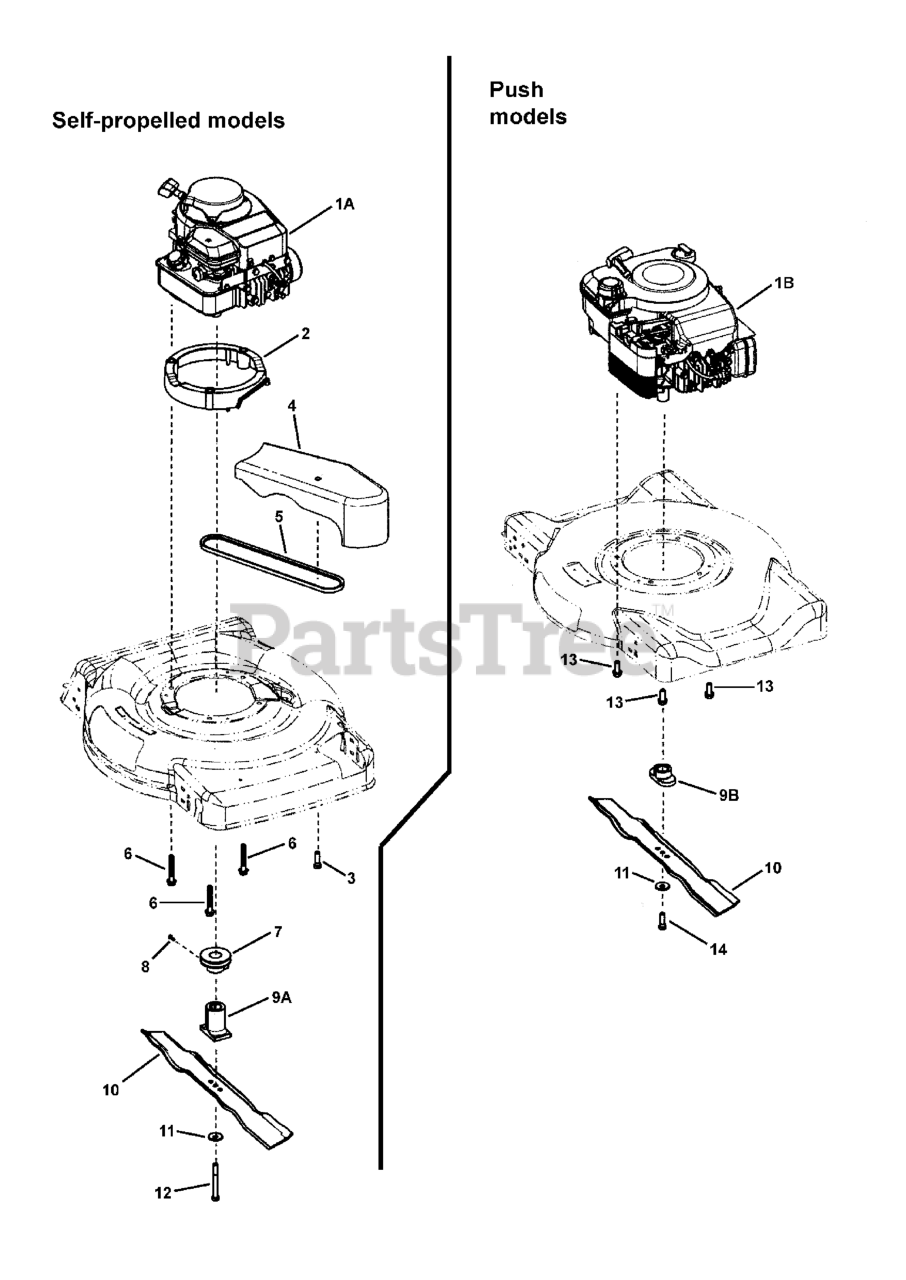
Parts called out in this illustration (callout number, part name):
1A	* ENGINE, B&S, 650 Ser, B1, X-Spec
1A	* ENGINE, B&S, 675 Ser, B1, FC, X-Spec
1B	* ENGINE, B&S, 550 Ser, B3, X-Spec
2	** ASSEMBLY, Engine Spacer, 22" WBM, Propelled
3	SCREW, #10-24 x 2-1/2
4	COVER, Belt, Plastic
5	BELT, Drive, SS, 3L sect. 33-3/4 Long
6	BOLT, Hex Washer, 3/8-16 x 2-1/2
7	PULLEY, Engine
8	SCREW, Poly, #8-11 x 5/8
9A	HUB, Blade, Self Propelled
9B	HUB, Blade, Push
11	WASHER, Bellville, 3/8 ID x 1-1/8 OD
12	BOLT, Hex Head, 3/8-24 x 3-1/4, GR 8
13	SCREW, Hex Washer, Self Tap, 3/8-16 x 1
14	CAPSCREW, Hex Head, 3/8-24 x 1-1/4, GR 5
